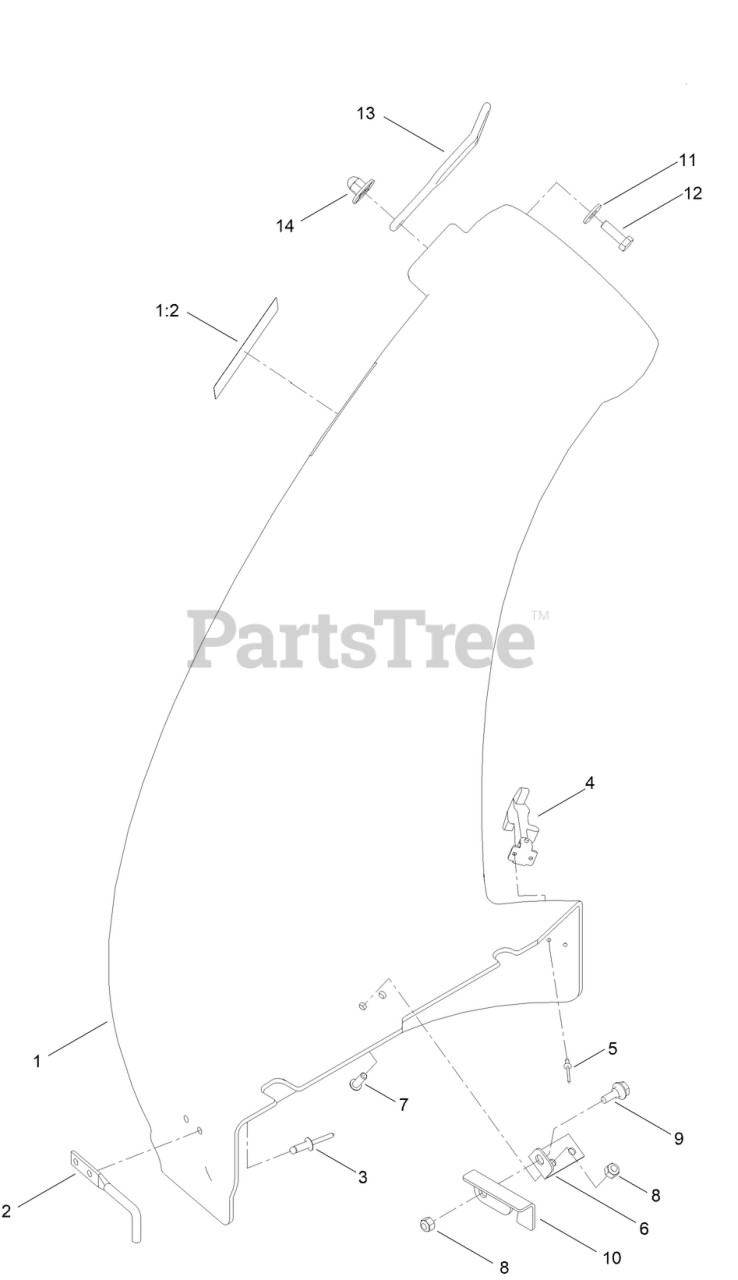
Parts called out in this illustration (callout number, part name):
1	34 IN BAGGER BOOT ASM
1:2	DECAL-DANGER
2	HOOK-BOOT
3	RIVET-BLIND
4	HANDLE ASM
5	RIVET-POP
6	PLATE-PIVOT
7	SCREW-HSBH
8	NUT-LOCK, NI
9	SCREW-SHOULDER,HWH
10	PLATE-LATCH
11	WASHER-FLAT
12	SCREW-HH
13	RETAINER-DUCT
14	NUT-IMPELLER
